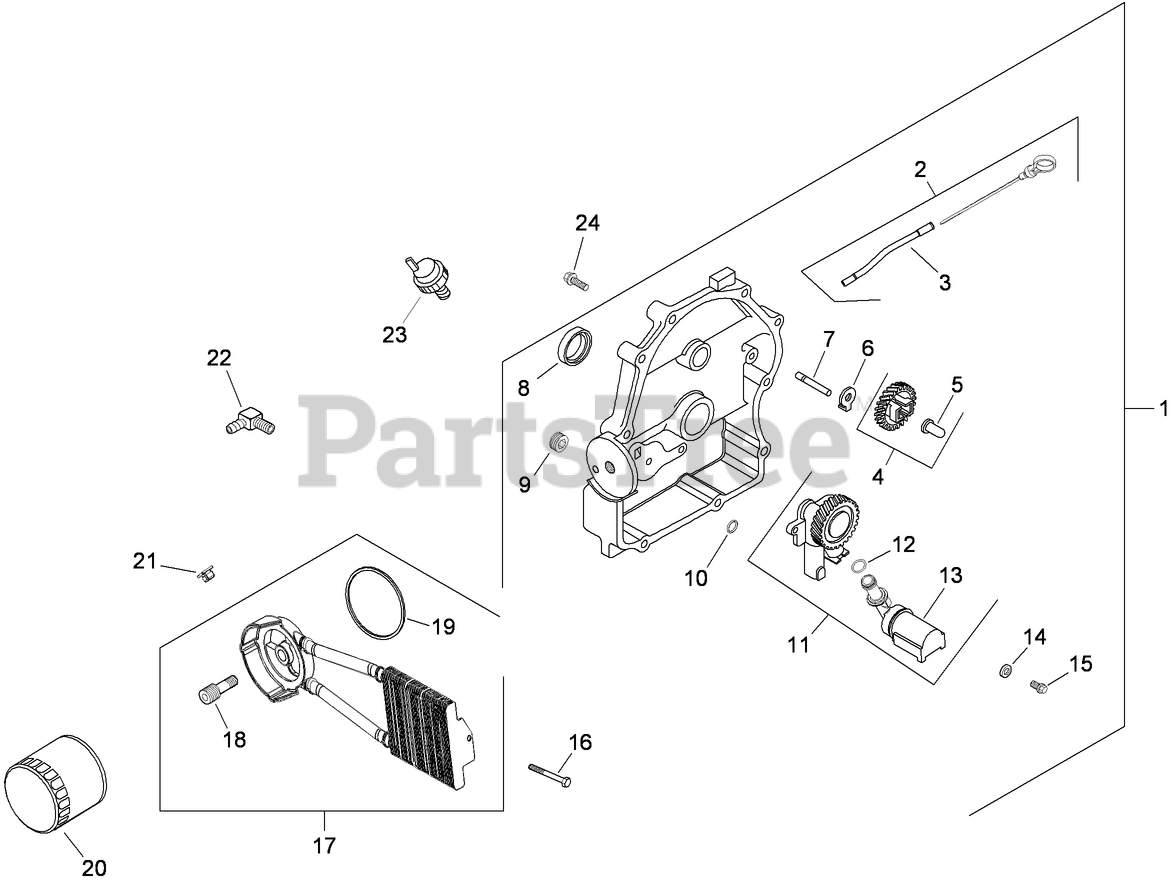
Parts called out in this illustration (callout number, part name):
1	CLOSURE PLATE and BEARING ASM (INCLUDES 2-15)
2	DIPSTICK AND DIPSTICK TUBE ASM (INCLUDES 3)
3	Dipstick
4	GOVERNOR GEAR W/PIN KIT (INCLUDES 5)
5	PIN-REGULATING, GOVERNOR
6	TAB-LOCKING
7	SHAFT-GEAR, GOVERNOR
8	SEAL-OIL
9	PLUG-PIPE, COUNTERSUNK (1/8)
10	O-Ring
11	OIL PUMP ASM (INCLUDES 12, 13)
12	O-RING
13	TUBE-PICK UP, OIL
14	WASHER-FLAT (6 MM)
15	SCREW-FLANGE, THREAD FORMING (M6X1.0X25)
16	SCREW-TAPPING
17	OIL COOLER KIT (METAL) (INCLUDES 18, 19)
18	NIPPLE-FILTER, OIL
19	O-RING
20	FILTER-OIL
21	NUT-PLASTIC (BLACK)
22	Connector-Hose, 90 Deg
23	SWITCH-PRESSURE, OIL
24	SCREW-FLANGE (M8X1.25X45)
